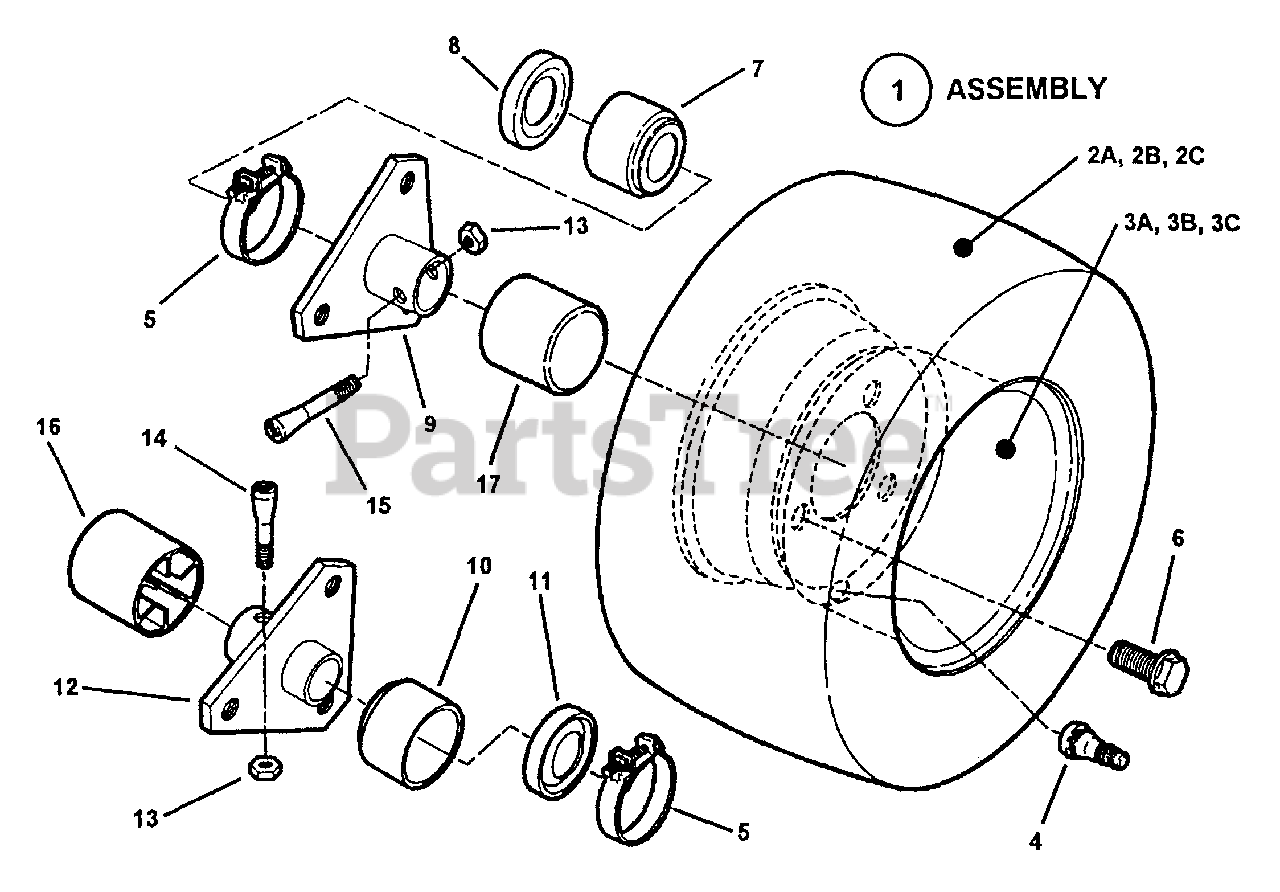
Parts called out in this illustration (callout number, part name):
1	ASSEMBLY, Rear Tire & Rim
2A	TIRE, Wide, 16/6.50 x 8 Turf
2B	TIRE, 4.80/4.00 Turf Saver
2C	TIRE, 16 x 6.50-8 Carlisle
3A	RIM, Wide
3B	RIM, 4.80/4.00 x 8, 3 Lug
3C	RIM, 8 x 5.375, Carlisle
4	VALVE, Air (Snap-in)
5	CLAMP
6	BOLT, 1/2-20 x 3/4" Lug
7	CAP, Seal (Right Hand)
8	SEAL, Oil (Right Hand)
9	HUB, Rear Wheel (Right Hand)
10	CAP, Seal L.H. 3/4"
11	SEAL, Oil (Left Hand)
12	HUB, Rear Wheel (Left Hand)
13	NUT, 5/16-24 Hex Center Lock
14	BOLT, 5/16-24 x 1-5/8" Tapered (Left Hand)
15	BOLT, 5/16-24 x 2" Tapered (Right Hand)
16	CAP, Hub (Left Hand)
17	CAP, Hub (Right Hand)
